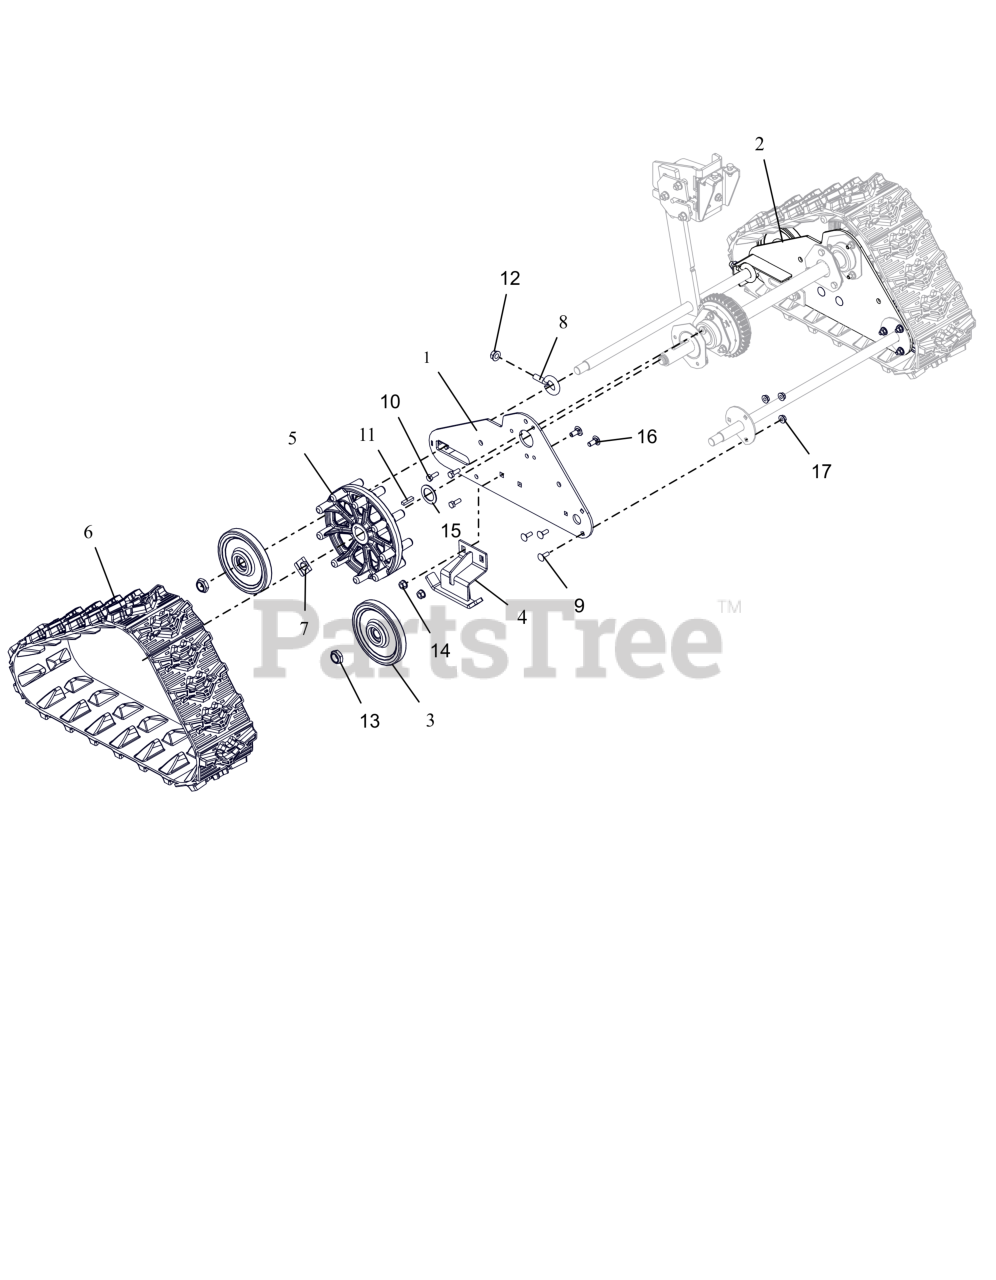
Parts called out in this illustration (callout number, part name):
1	SIDE PLATE, RH-TRACK
2	SIDE PLATE, LH-TRACK
3	WHEEL, BOGIE - SINGLE BEARING
4	RUNNER, GUIDE-TRACK
5	WHEEL, MACHINED DRIVE
6	TRACK, RUBBER
7	CLIP, SNAP .625 DIA
8	BLT-EYE .375-16X.880 YWZC
9	BLT, RHSN .25-20X.750 G5 ZCC
10	BLT, HEX .25-20X.75 G5 ZCC
11	KEY-RECT .25X.188X1.00
12	NUT-LK-CTR-FLG .375-16 GF ZCC
13	NUT, NYL LK .625-18 ZCC
14	NUT-LK-TOP-FLG .312-18 GF ZCC
15	WSHR, FLT 1.010X1.505X.062 ZCC
16	BLT,RHSN .31-18X.75 G5 ZCC
17	NUT-LK-TOP-FLG .250-20 GF ZCC
